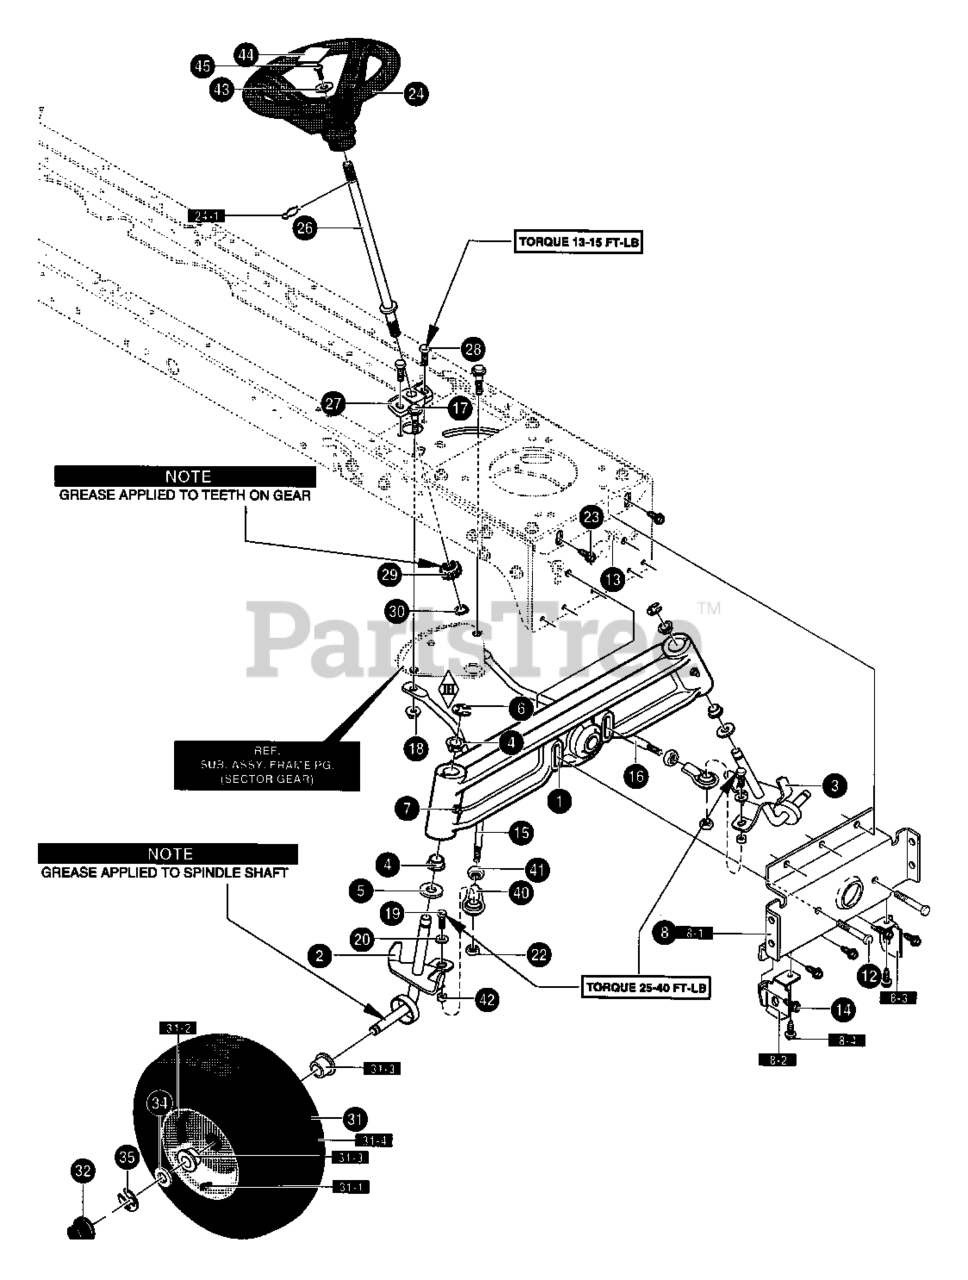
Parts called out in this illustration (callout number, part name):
1	AXLE, FRONT ASSEMBLY
2	SPINDLE, RH
3	SPINDLE, LH
4	BEARING, SPINDLE
7	ZERK, GREASE FITTING
8	FRONT AXLE/DECK HANGER
8-1	HANGER, AXLE
8-2	HANGER, DECK RH
8-3	HANGER, DECK LH
8-4	SCREW, 5/16-18 x 0.75
12	SCREW, 5/16-24 x 2.75
13	NUT, 5/16-24
14	SCREW, 5/16-18 x 0.75
15	ROD, DRAG LINK
16	ROD, DRAG LINK
18	NUT, 3/8-16
20	WASHER, FLAT
22	NUT, 3/8-16
23	SCREW, 5/16-18 x 0.75
24	STEERING WHEEL
24-1	RETAINER, SPRING
26	SHAFT, STEERING
27	BEARING-LOWER
28	SCREW, 5/16-18 x 0.75
29	GEAR, PINNION
30	RING, RET
31	TIRE & RIM 15X6-6
31-1	VALVE STEM
31-2	RIM, CARLISLE
31-3	BEARING
31-4	TIRE, 15X6X6
32	HUB CAP
35	"E" RING
40	TIE ROD
41	NUT 1/2-20
42	SPACER, SLEEVE
43	FLATWASHER
44	INSERT, STEERING WHEEL
